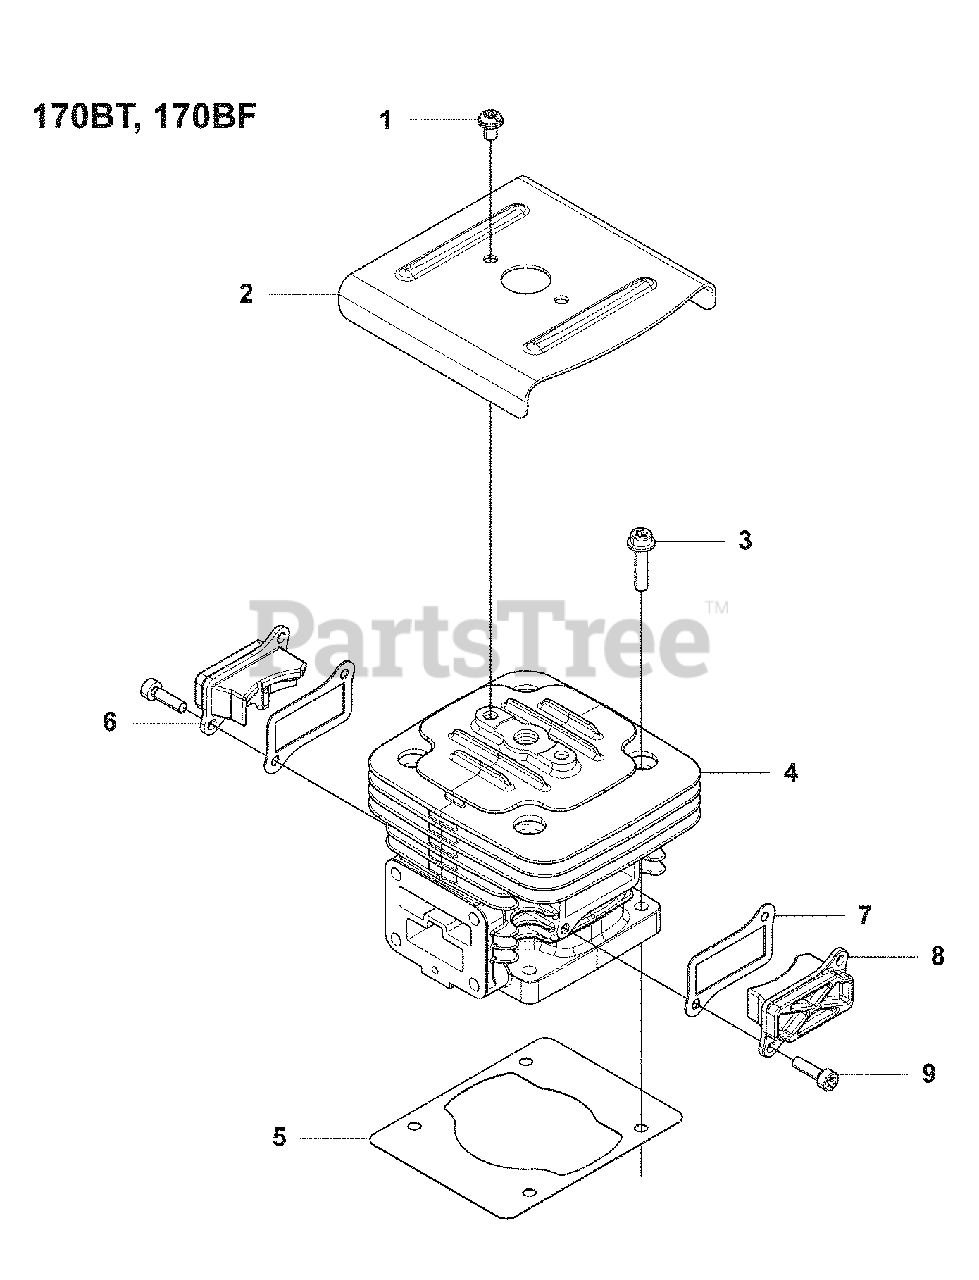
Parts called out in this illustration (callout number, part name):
2	Plate
3	Torx Bolt
5	Gasket
6	Cover, TR F
7	Gasket
8	Cover, Tr-S
9	Torx Bolt, M4 X L16
